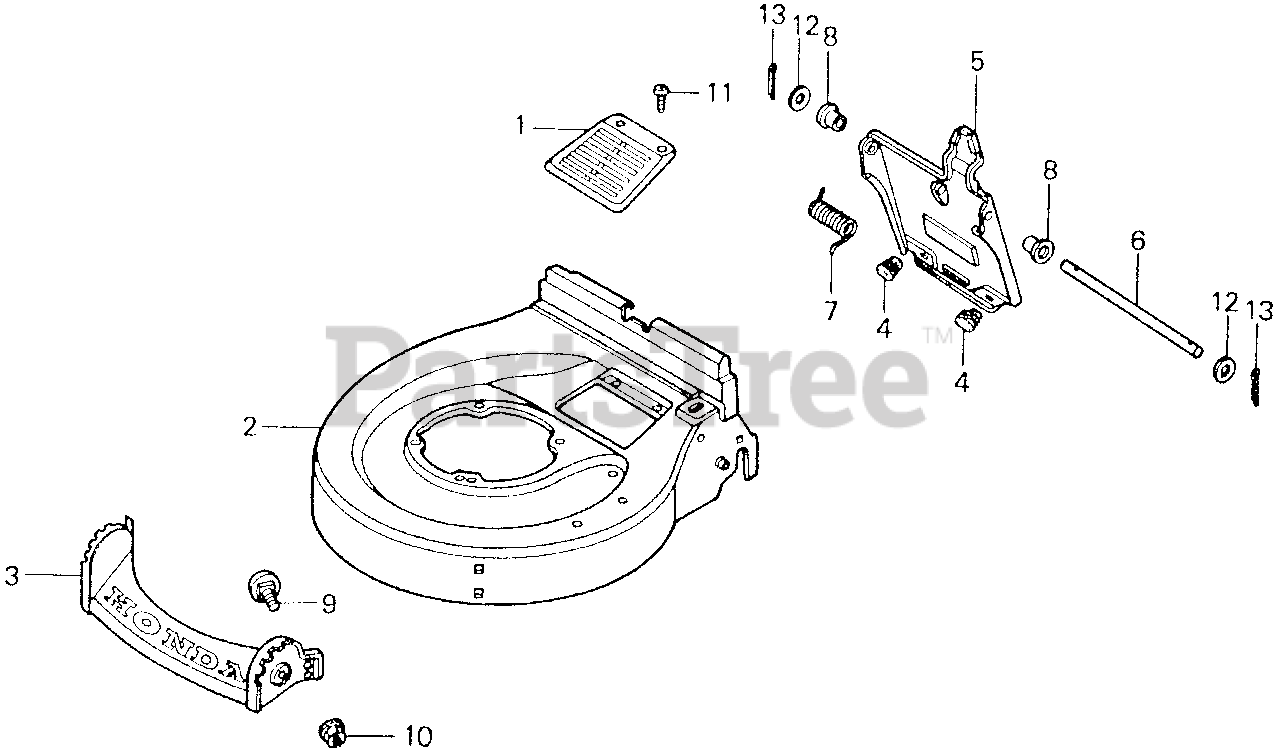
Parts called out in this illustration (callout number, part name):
1	COVER, BELT
2	HOUSING, CUTTER
3	GUARD, FR.
4	STOPPER, DISCHARGE GUARD Use up to Frame SN 1186736.
5	GUARD, DISCHARGE
6	SHAFT, DISCHARGE GUARD
7	SPRING, GUARD RETURN (NOT AVAILABLE)
8	BUSH, DISCHARGE GUARD
9	BOLT, SPECIAL (9X15)
10	NUT, FLANGE (8MM)
11	SCREW, TAPPING (5X8)
12	WASHER, PLAIN (8MM)
13	PIN, COTTER (2.0X15)
